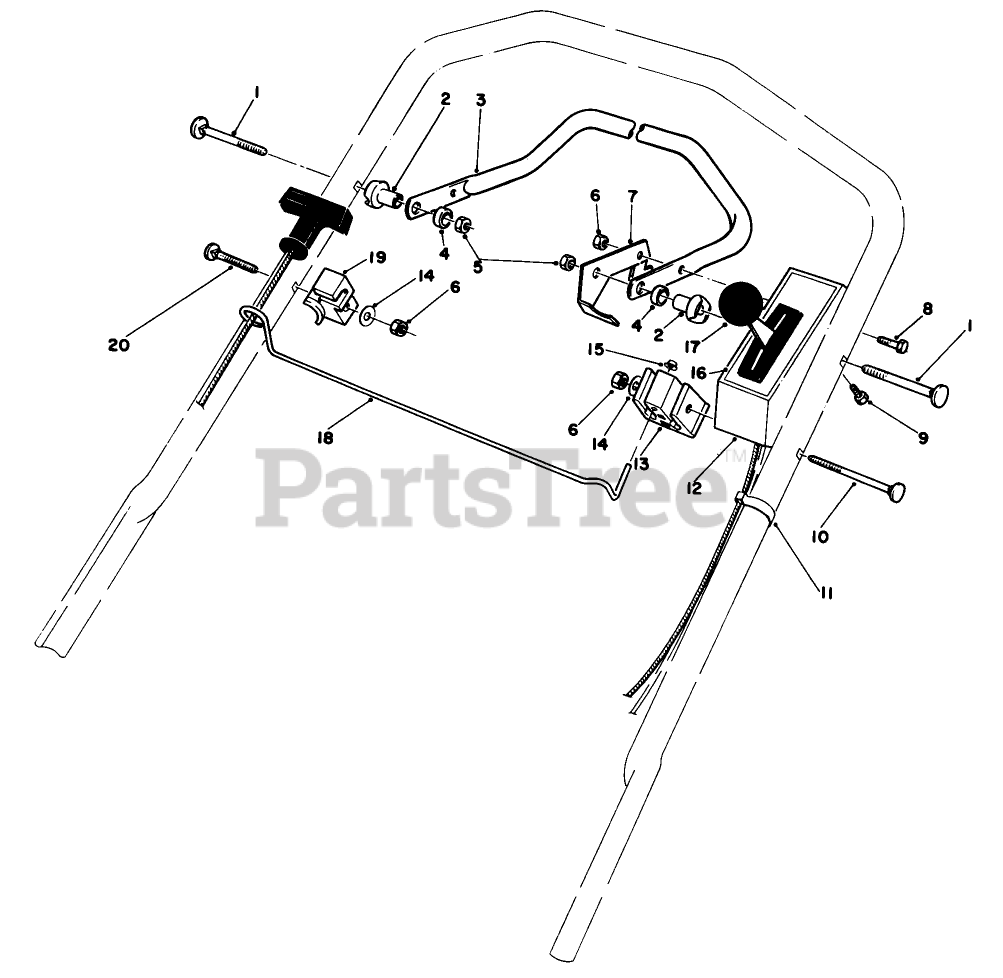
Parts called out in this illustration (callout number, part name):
2	SPACER-SUPPORT
4	SPACER-NYLON
5	NUT-LOCK, NI
6	NUT-LOCK, NI
8	SCREW-HH
9	SCREW-HWHTF
10	HANDLE SCREW
11	BOWDEN CLIP
13	SUPPORT-CABLE
14	WASHER-FLAT
15	NUT-SPEED
17	SERVICE THROTTLE CONTRO
19	ROD CATCH
20	SCREW-HANDLE
